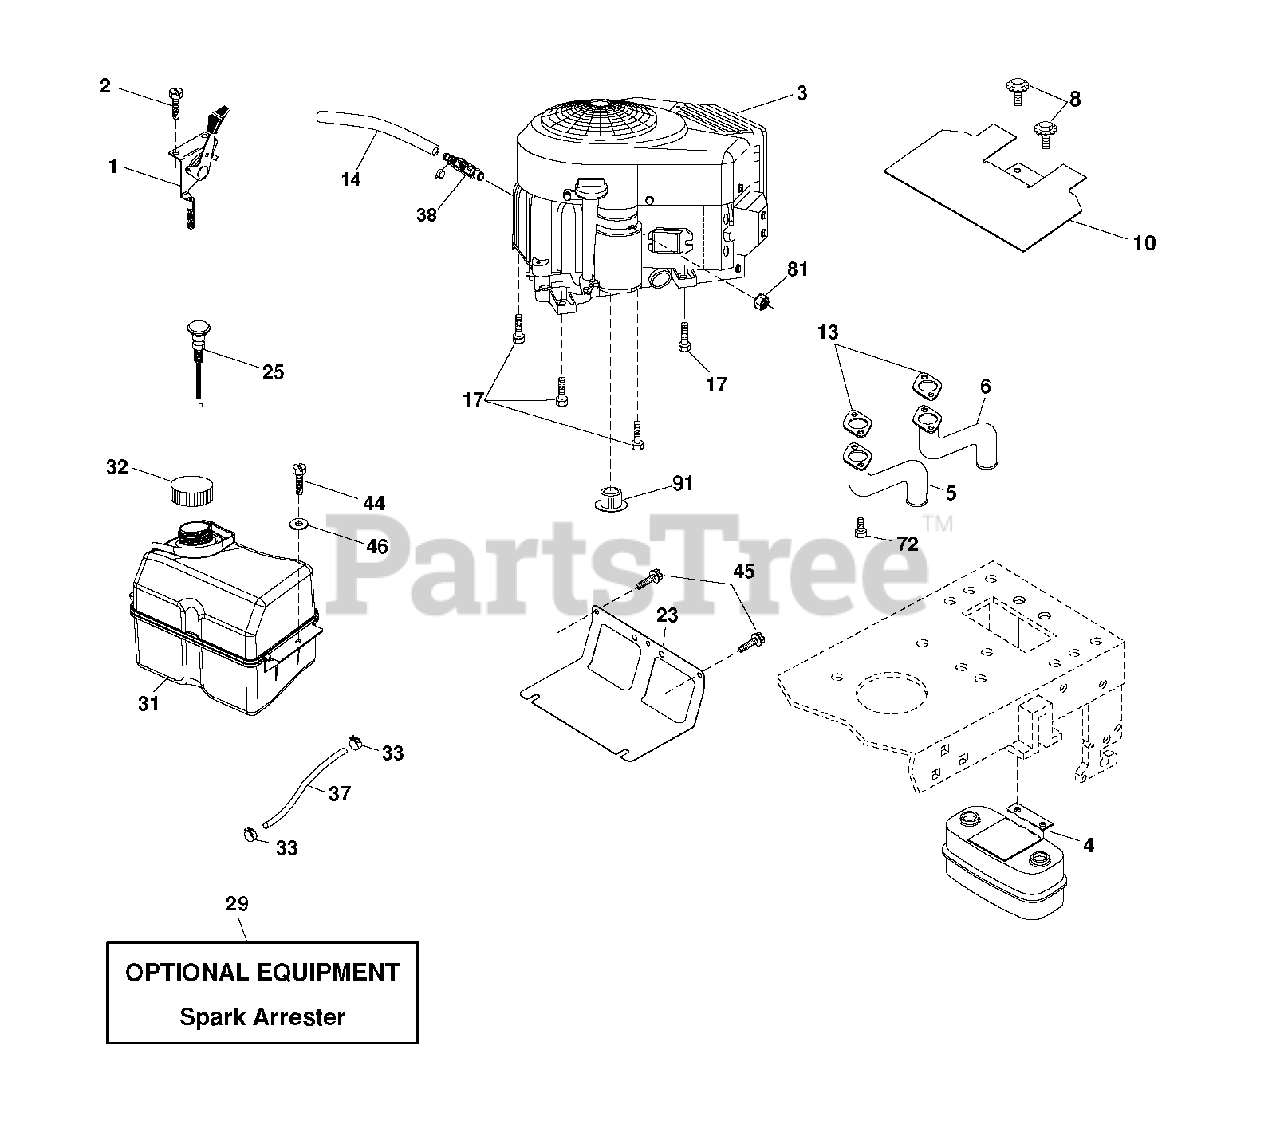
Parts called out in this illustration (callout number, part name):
1	THROTTLE CABLE
2	SCREW.#10 X 0.750.BOS THREAD
4	MUFFLER.TWIN.CYL.LOW.TONE
5	EXHAUST TUBE RH
6	TUBE MANIFOLD LH
8	BOLT, 5/16-18 X 1 3/4
10	RP SHIELD HEAT MUFFLER
13	GASKET.MUFFLER
14	TUBE, DRAIN OIL ASM.
17	SCREW.3/8-16
23	SHEILD.BROWNING.DBR.GUARD
25	CONTROL CHOKE
29	ARRESTER SPARK (OPTIONAL)
32	CAP.FUEL.2.25"VENTED"
33	HOSE CLAMP
37	LINE.FUEL.20
38	VALUE.OIL.DRAIN
44	SCREW HEXWSHR 1/4-20X3/4
45	SCREW, 3/8-16X3/4
72	SCREW.SOCKET.HEAD.5/16-18
81	NUT
91	BUSHING.1.375OD
